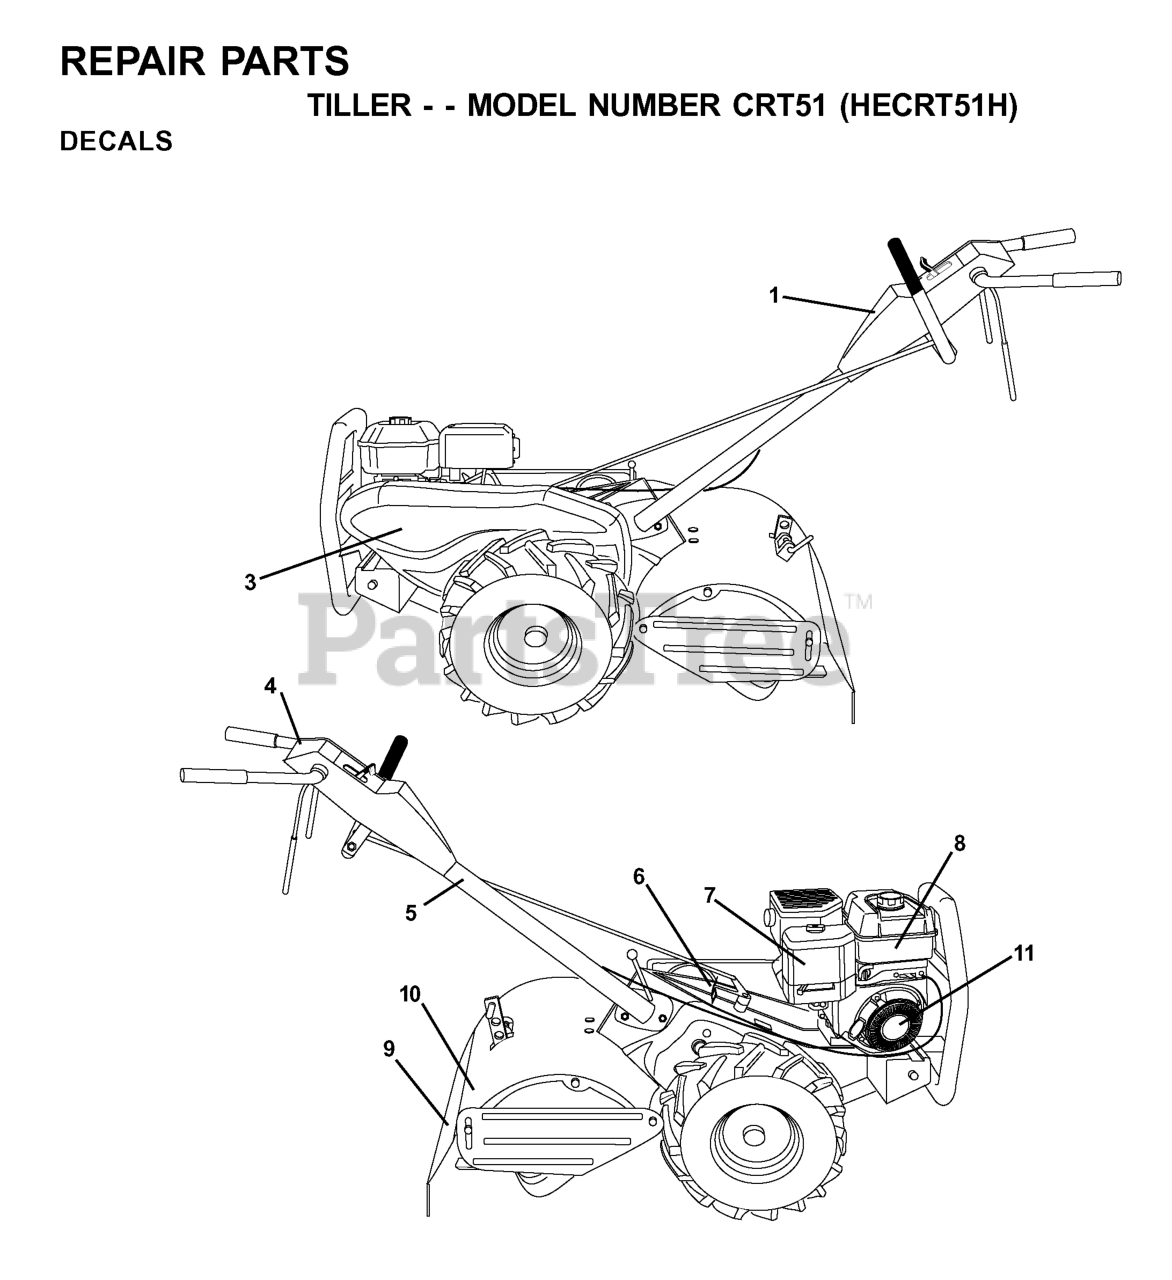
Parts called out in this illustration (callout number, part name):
1	DECAL, LOGO
4	DECAL, LOGO
5	DECAL.PLACEMENT.HAND.SYMBOLS
6	DECAL.SHIFT.INDICATOR.TILLER
8	DECAL, ENGINE INTEK REF
9	DECAL.WARNING.4-SYM.TILLER.INT
10	DECAL EUROPE STANDARD CE
11	DECAL.REWIND
